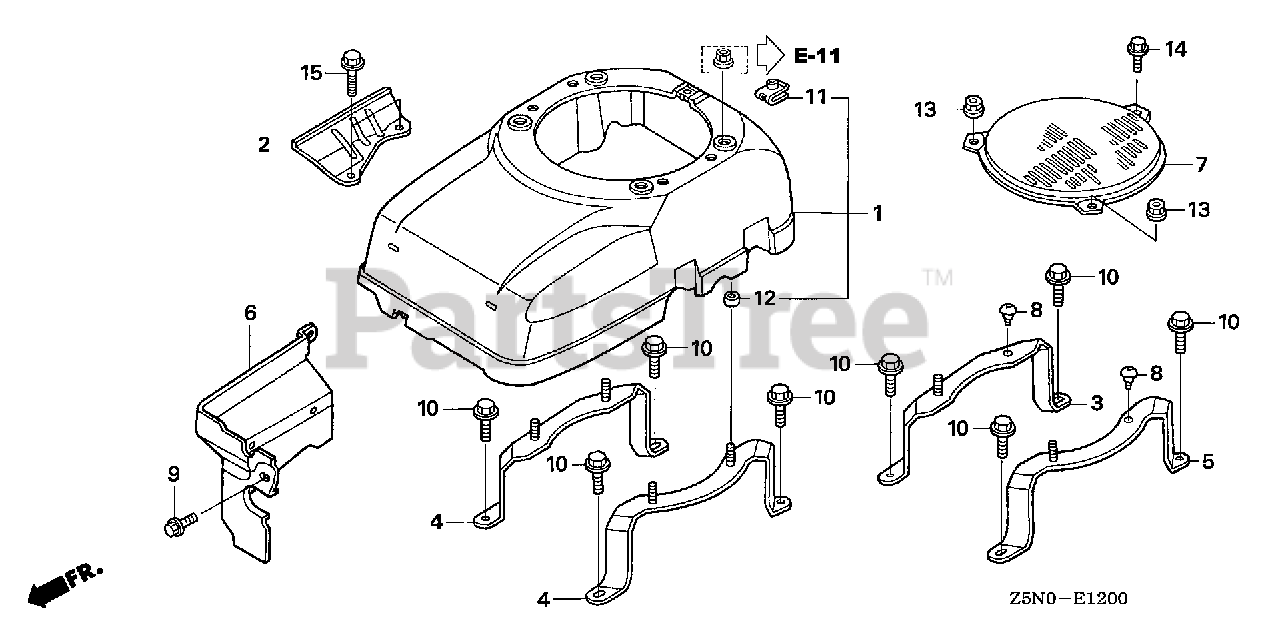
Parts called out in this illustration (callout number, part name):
1	COVER, FAN *NH1* (BLACK)
4	BRACKET, FAN COVER
10	BOLT, FLANGE (6X16) (CT200)
12	COLLAR, FAN COVER
